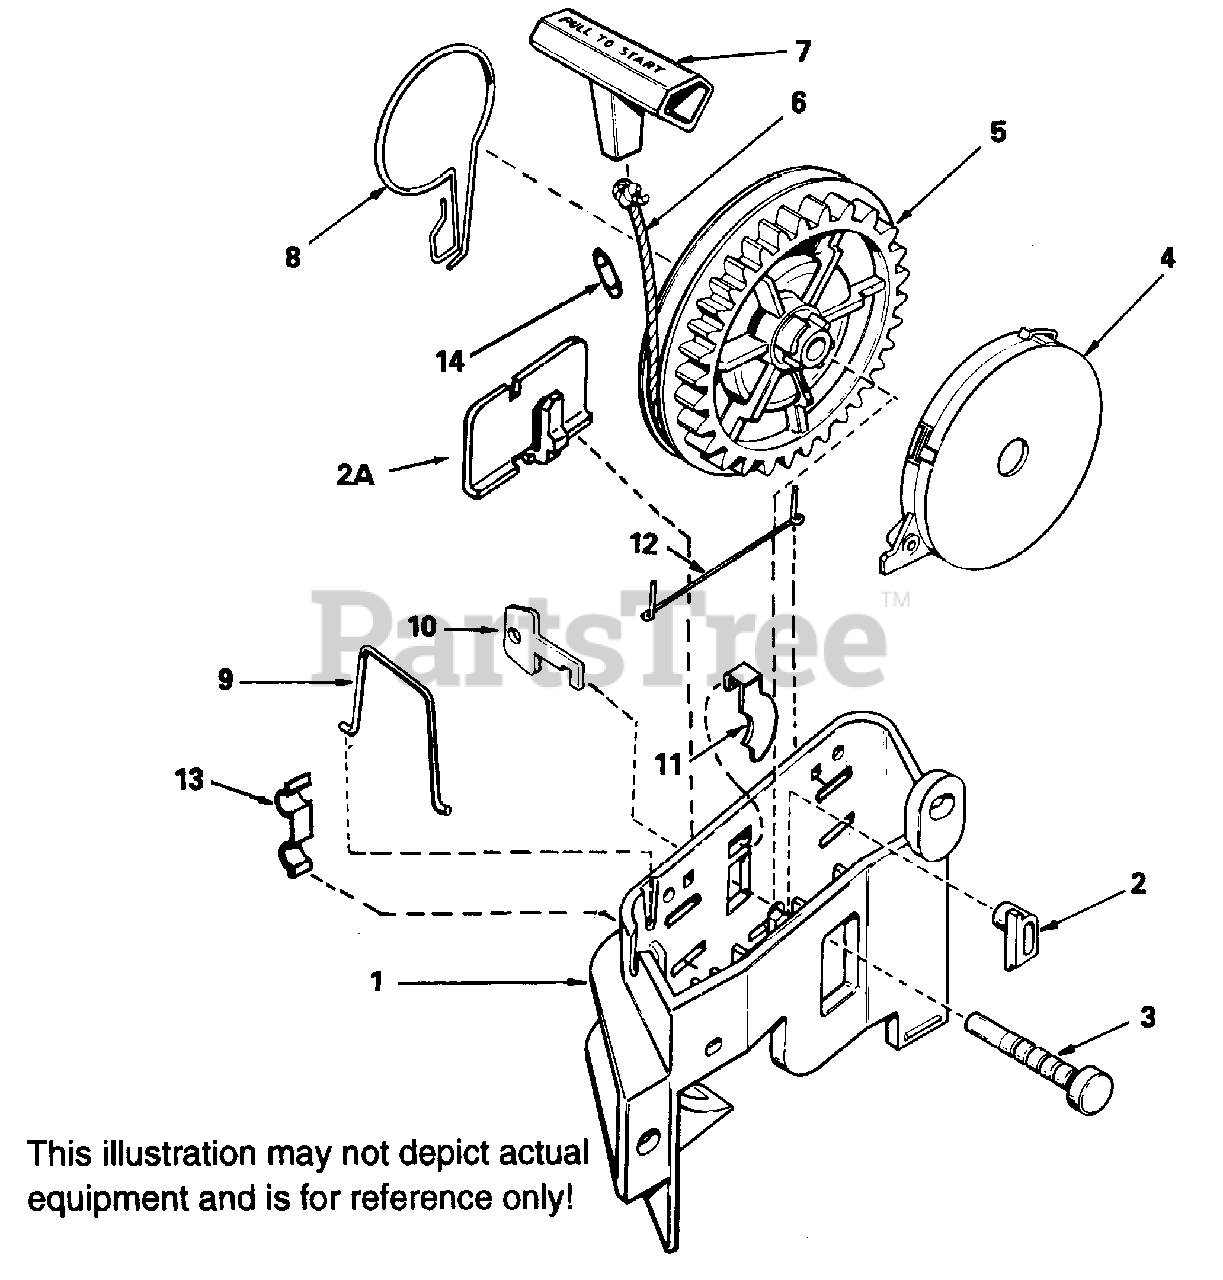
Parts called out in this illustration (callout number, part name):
1	Starter Bracket
2	Locking Pawl
3	Pulley Pin
4	Rewind Spring Ass'y. (Incl. 3)
6	Starter Rope Length 98" x 9/64" dia.
7	Starter Handle
8	Brake Spring
9	Rope Clip
11	Starter Pawl
12	Pawl Spring
14	Rope Stop & Staple
